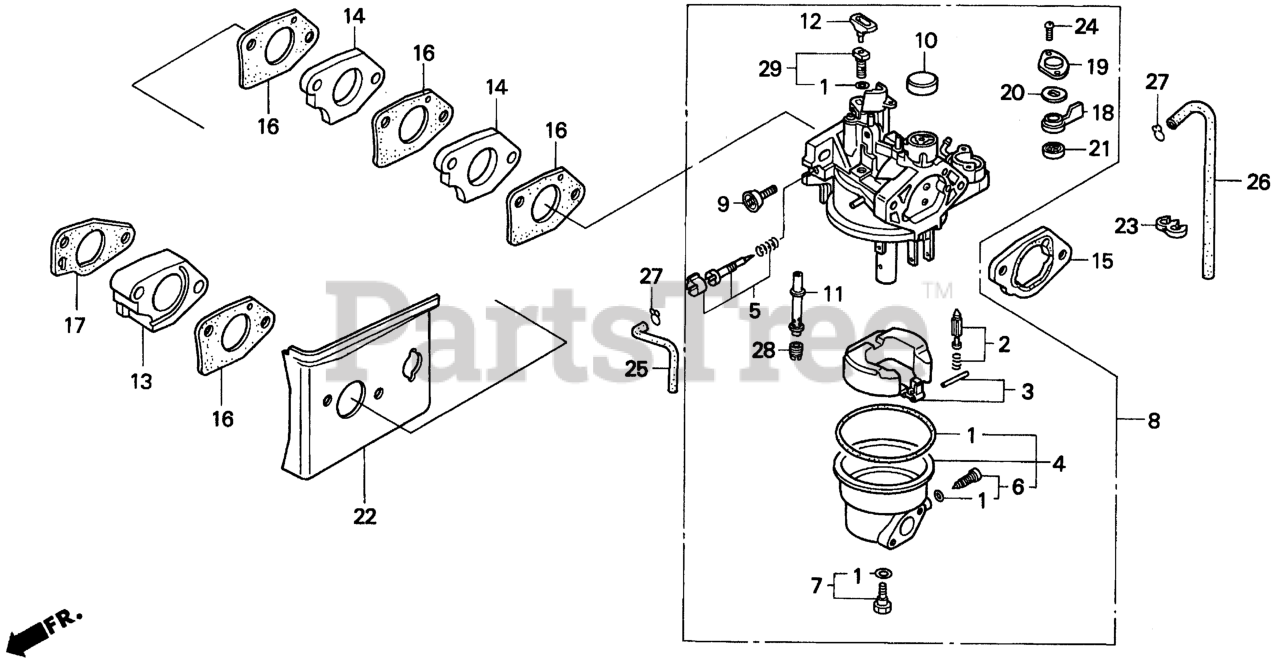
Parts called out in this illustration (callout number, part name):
1	GASKET SET
2	VALVE SET, FLOAT
3	FLOAT SET
4	CHAMBER SET, FLOAT
5	SCREW SET (Honda Code 4219879). (CARBURETOR NO.)
6	SCREW SET, DRAIN (ADVENTURE GREEN) (CARBURETOR NO.)
7	BOLT KIT, FUEL CHAMBER
8	CARBURETOR ASSY. (BE86D B)
9	SCREW, THROTTLE STOP
10	CAP, CHOKE LEVER DUST
11	NOZZLE, MAIN
12	COLLAR, SET
13	INSULATOR, CARBURETOR
14	INSULATOR, CARBURETOR
15	SPACER, CARBURETOR
16	GASKET, CARBURETOR
17	GASKET, INSULATOR
18	LEVER, VALVE
19	PLATE, LEVER SETTING (CARBURETOR NO.)
20	SPRING, PETCOCK LEVER (CARBURETOR NO.)
21	GASKET, VALVE
22	GUIDE, AIR
23	CLIP, IGNITION WIRE
24	SCREW, PAN (3X6)
25	BULK HOSE, FUEL (4.5X3000) (Honda Code 5137104). (4.5X140)
26	BULK HOSE, FUEL (4.5X3000) (Honda Code 5137104). (4.5X140)
27	CLIP, TUBE (B8)
28	JET, MAIN (#88) Use up to Engine SN BE81B B.
28	JET, MAIN (#90) Use from Engine SN BE81B C.
28	JET, MAIN (#92)
29	JET SET, PILOT (#40) (ADVENTURE GREEN) (CARBURETOR NO.)
